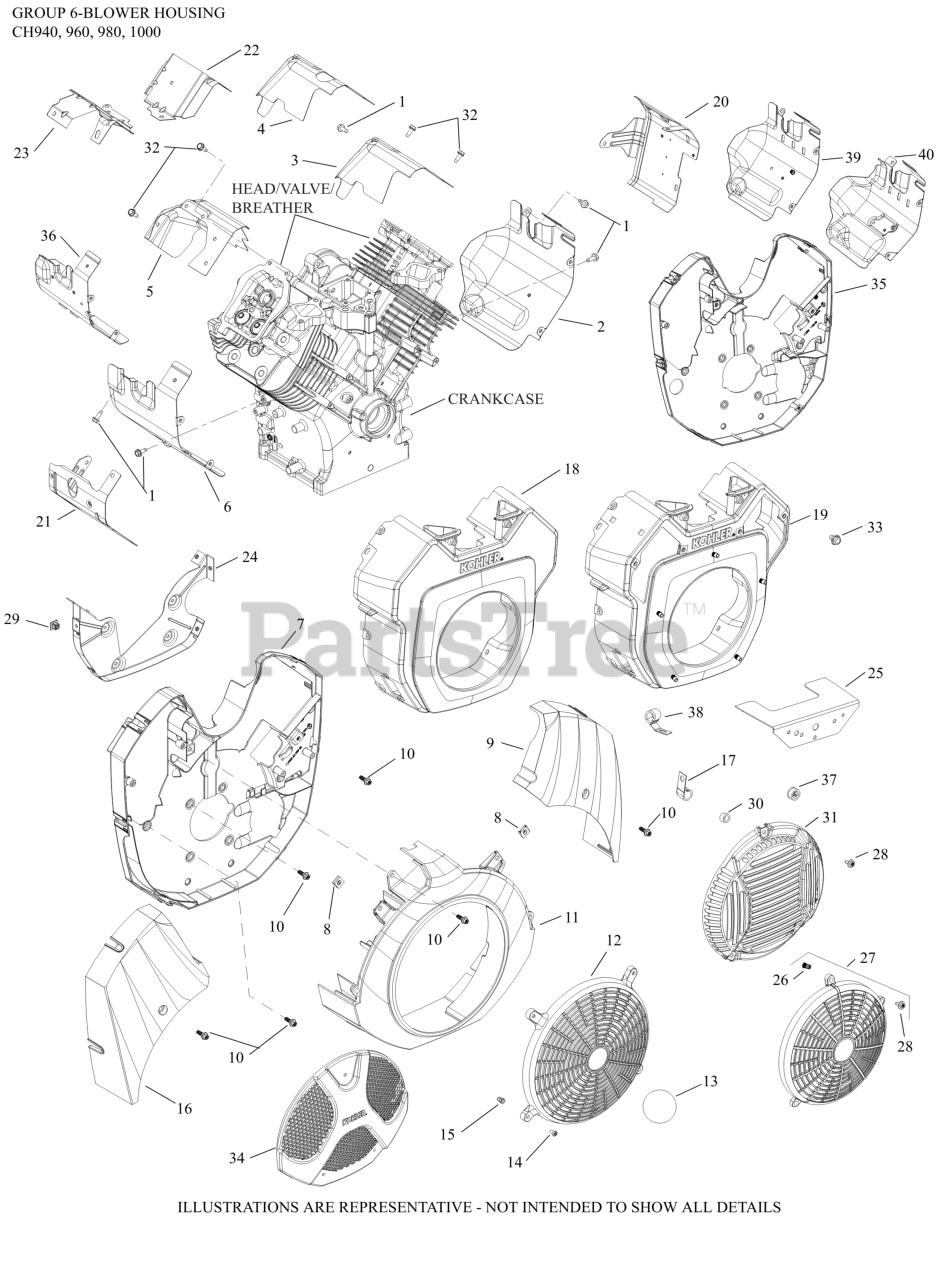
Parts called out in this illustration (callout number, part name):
1	SCREW, THREAD FORMING
2	BAFFLE, CYL BARREL #1 SIDE
3	BAFFLE, VALLEY #1 SIDE
5	BAFFLE VALLEY #2 SIDE
6	BAFFLE CYL BARREL #2 SIDE
7	SHROUD AND CLIP ASSEMBLY
8	CLIP, BAFFLE MOUNTING
9	SHROUD, #1 CYLINDER
10	SCREW, SHD THD FRM
11	HOUSING, BLOWER-USE 62 027 07-S
16	SHROUD, #2 CYLINDER-USE 62 424 13-S
